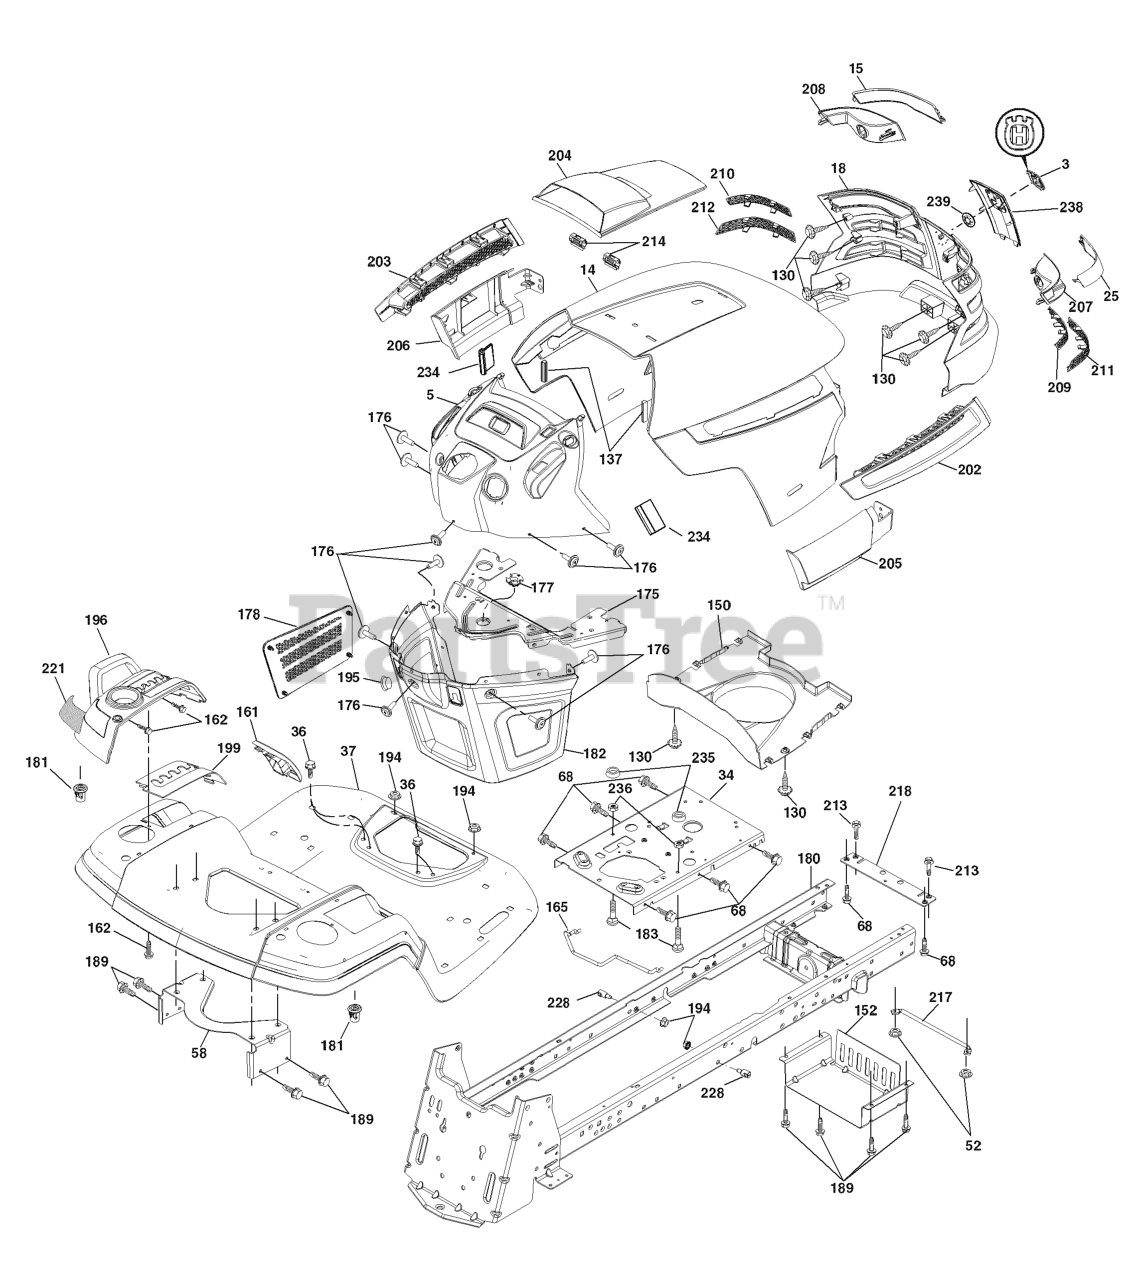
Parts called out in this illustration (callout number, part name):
3	RP LOGO
5	DASH.ASM.HUSQ.GT.E.RECT.W/CK
14	HOOD
15	LENS.LH.TEX.GT.HUSQ.CL
18	GRILL.ASM.HUSQ.TG/CRD.W/TRIM
25	LENS.RH.TEX.GT.HUSQ.CL
34	PLATE.ENGINE.WELDED.CHASSIS
36	SCREW 5/16"
37	FENDER.PNT.TX.GT.CH/FW.ORANGE
52	LOCKNUT
58	BRKT.SUPPORT.FNDR/TANK
68	Screw 5/16-18 x 1/2
130	SCREW.#10 X 0.750.BOS
137	BUMPER DASH
150	AIR.DUCT.HOOD.TEX.GT.HUSQ
152	SHIELD.BROWNING.W/TEX
161	CONSOLE.FUEL.WINDOW.HU
162	SCREW.HI-LO.CONSOLE
165	SUPPORT.TANK.REAR.W/TEX
175	PLATE.CROSSMEMBER.HUSQ
176	SCREW.#10-24X5/8.RN.QU
177	BUSHING, STEERING
178	CARGO.ASM.NET.TXGT.W/C
180	CHASSIS.GT.SLOPED.DRAWBAR.
181	BUSHING.MNT.FEND.CRGO.
182	DASH.LOWER.COMMON.12V.ADAPTOR
183	BOLT.5/16-18X1-1/4 FULL.THREAD
189	SCREW
194	NUT LOCK HEX FLANGE 5/16-18
195	PLUG.N/CRUISE.COMMON.YT/GT.BLK
196	CONSOLE.ASM.DCKLFT.W/RF.HQ.DLR
199	PLATE.DECK.LIFT.HUSQVARNA.GT
202	VENT.SIDE.HOOD.HUSQ.RH.GREY
203	VENT.SIDE.HOOD.HUSQ.LH.GRAY
204	HOOD VENT
205	SKIRT.HOOD.SIDE.HUSQ.RH.GREY
206	SKIRT.HOOD.SIDE.HUSQ.LH.GREY
207	BEZEL.RH.TEX.GT.HUSQ
208	BEZEL.LH.TEX.GT.HUSQ
209	INSERT.HEX.GRILL.HUSQ.GREY
210	INSERT.HEX.GRILL.HUSQ.
211	INSERT.HEX.GRILL.HUSQ.
212	INSERT.HEX.GRILL.HUSQ.
213	BOLT
214	CLIP.RETAINER.TINNER.
217	ROD.PIVOT.HOOD
218	X-PIECE.HOOD.STOP.NON/
221	REFLECTOR.LH.TEX GT HU
228	STUD.FASTNER.W/ANTI-ROTATE
234	BUMPER.HOOD.TEX.HUSQVARNA
235	SPACER FENDER
236	NUT.CENTERLOCK.5/16-
238	TRIM.HUSQ.TG/CRD.SERVICE
239	NUT PUSH M
